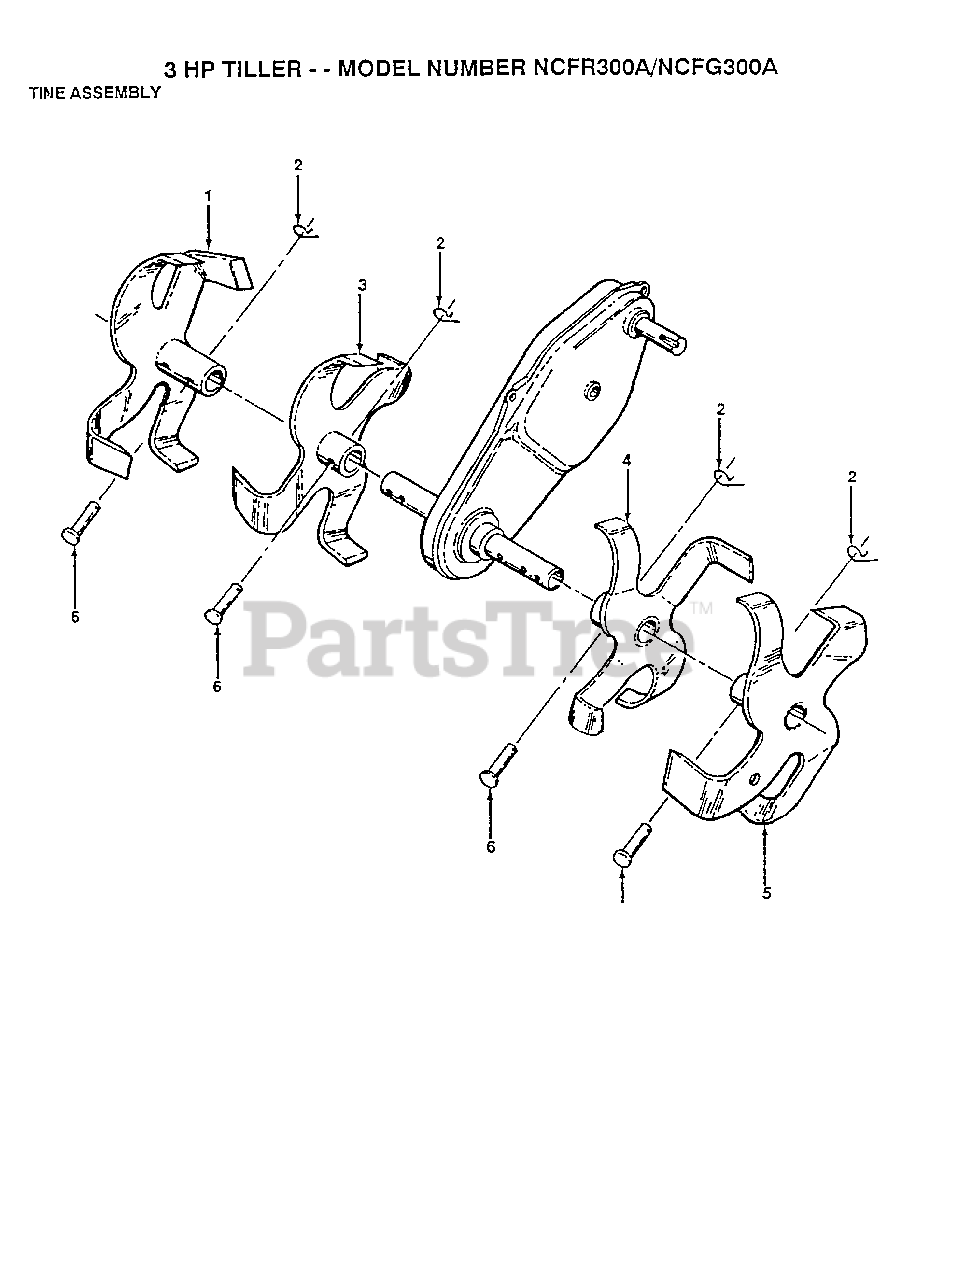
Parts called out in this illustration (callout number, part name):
1	TINE ASSY RH
2	SPRING.RETAINER
3	TINE ASSY RH
4	TINE INN LH TI
5	TINE ASS'Y LH
6	DRILLED RIVET RT
